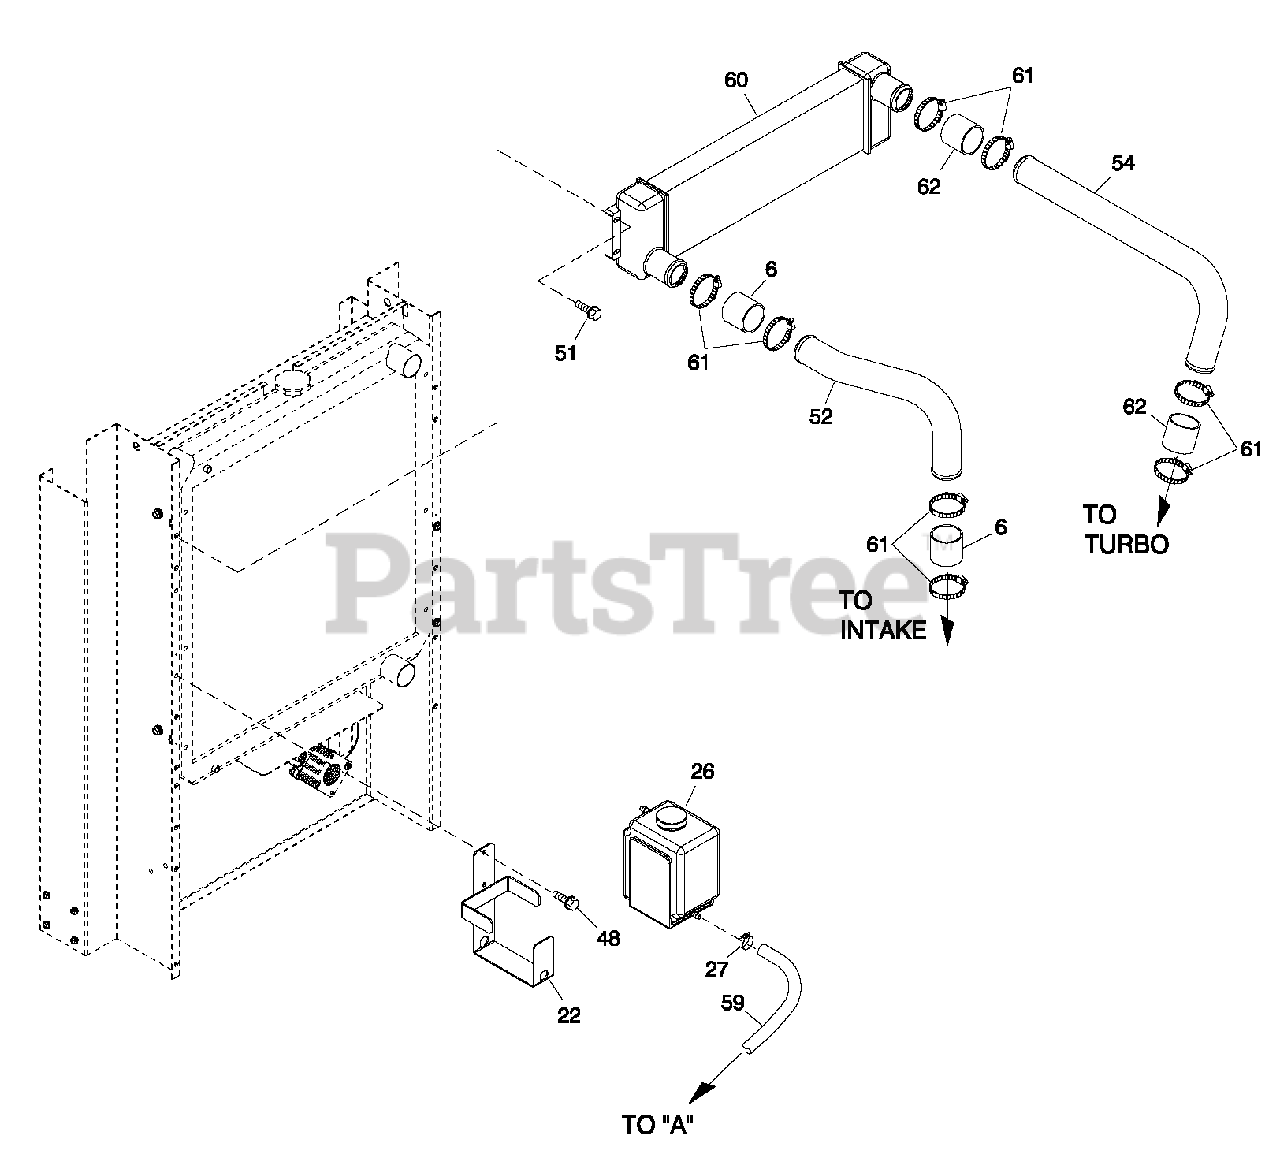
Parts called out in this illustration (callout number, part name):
6	HOSE 2"ID X 3.0"LG
22	BRACKET COOLANT TANK
26	TANK COOLANT RECOVERY
27	CLAMP HOSE BAND 1/4
48	SCREW THF M6-1 X 16 N WA Z/JS
51	SCREW THF M6-1 X 30 N WA DELTA
52	TUBE CAC OUT G2 TURBO
54	TUBE CAC IN
59	HOSE 9/32 ID (36" LG)
60	CAC 504W X 152H X 50D 2.4L G2
61	CLAMP CNST TENSION 1.75-2.625
62	HOSE 2 "ID X 3.0"LG
